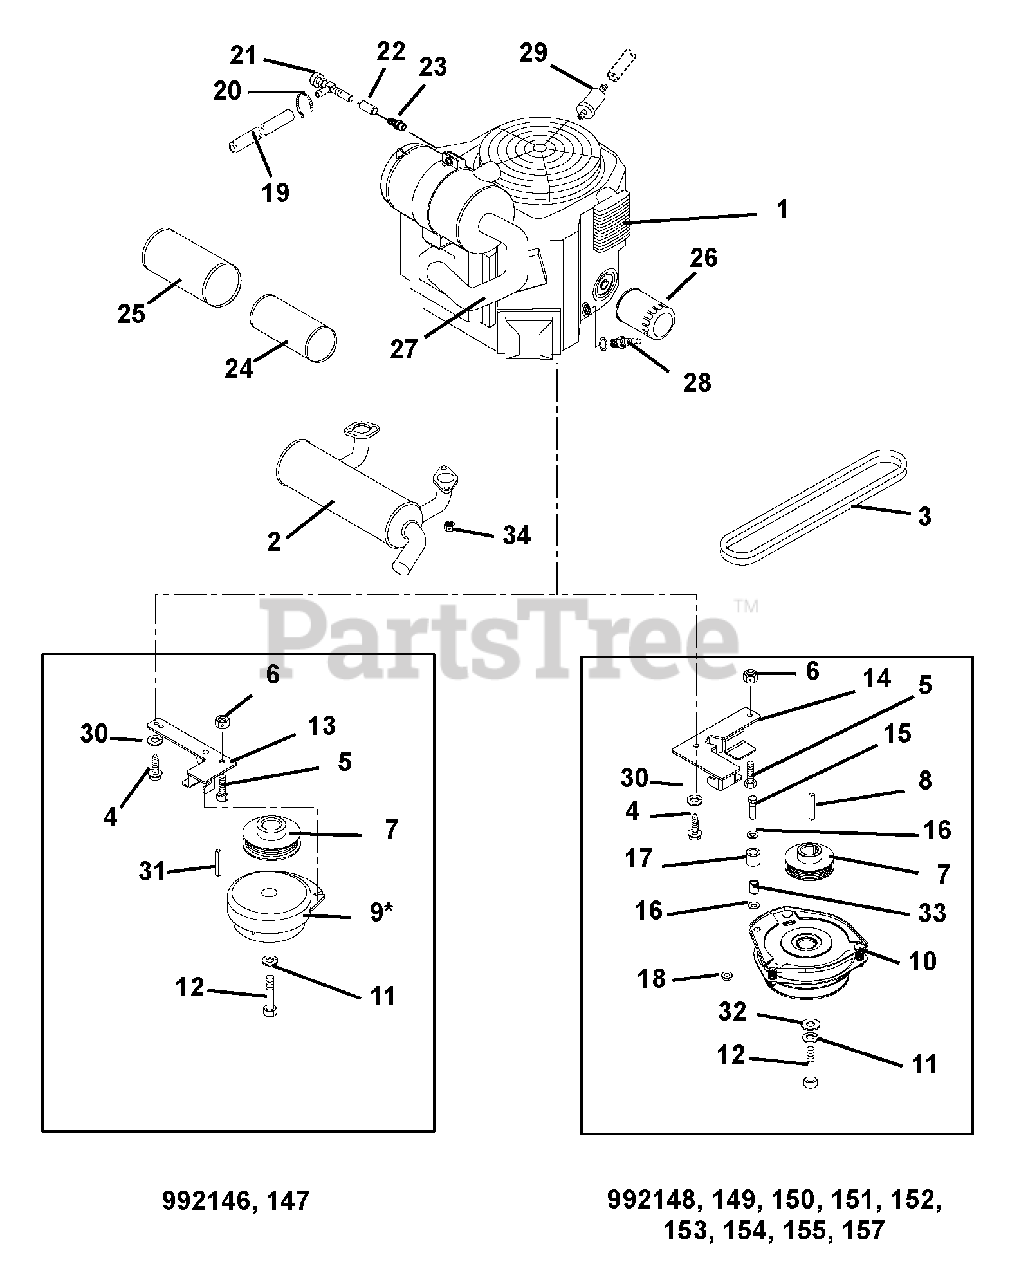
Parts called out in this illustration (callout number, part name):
1	Engine, 25hp Kawasaki
1	Engine, 26hp Liquid Cooled Kawasaki
1	Engine, 27hp Kohler
1	Engine, 23hp Kohler Command
1	Engine, 25hp Kohler Command
1	Engine, 30hp Kohler
2	Muffler, Kawasaki
2	Muffler, Kawasaki Liquid Cooled
2	Muffler, Kohler Twin
3	Belt, Poly-V
4	Screw, Tapping Hex Washer Head .38-16 x 1.50
4	Bolt, Hex M8-1.25 x 25 Grade 8
5	Bolt, Hex .31-18 x 1.75 Grade 5
6	Nut, Locking Top Flange .31-18
7	Sheave, Poly V 1.127 x 3.275
8	Key-Square .25 x 3.50 x .25 SAE
9	Clutch, Electric
10	Clutch, Electric
11	Washer, Locking .44 x .109
12	Bolt, Hex .44-20 x 3.00 Grade 5 YZ EP80
13	Anchor, Clutch
14	Anchor Clutch
15	Bolt-Hex .38-16 x 1.50 Grade 5
16	Washer-Flat-Steel .406 x .812 x .065
17	Bumper,Rubber .62 x 1.0 x .88 LG
18	Nut-Locking-Top-Flange .38-16
19	Gas Line, Bulk .25 I.D.
20	Cable Tie LG 5-1/2
21	Drain, 1/2" Drain
22	Adapter, .38 NPTF
23	Nipple
24	Element, Inner Safety
24	Air Filter
25	Element, Outer Primary
25	Elemtn, Pre-Cleaner
26	Oil Filter
27	Hose, Air Intake
28	Spark Plug
29	Fuel Filter
30	Washer, Lock .31 x .078
31	Key, Square .25 x 1 x 0.25
32	Washer, Flat Steel .469 x 2 x .25
33	Bushing, .407 x .625 x .813
34	Nut, Locking, Top M8-1.25
